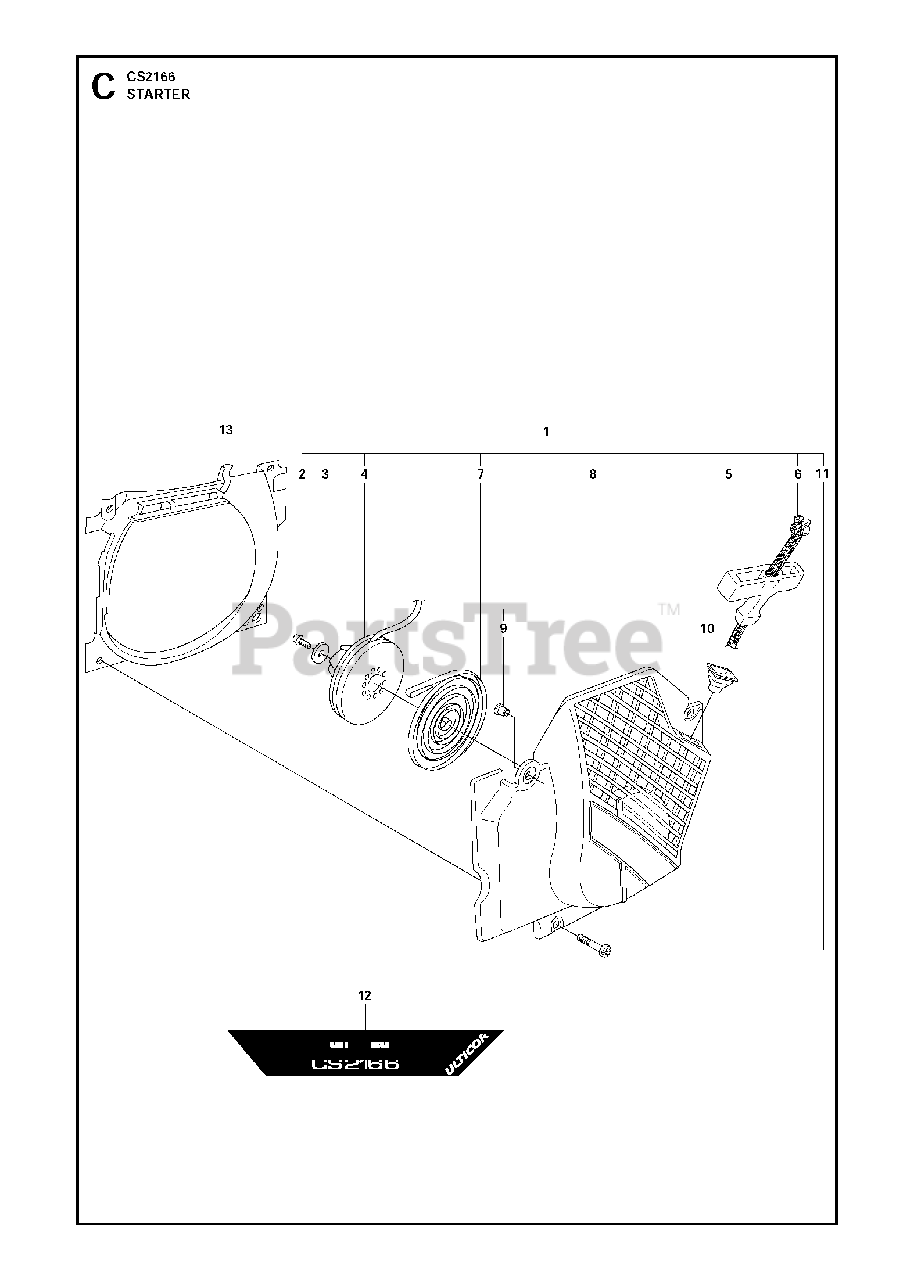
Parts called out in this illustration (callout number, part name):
1	STARTER ASSY
2	SCREW
3	WASHER
4	STARTER PULLEY
5	STARTER HANDLE
6	STARTER ROPE
7	SPRING
8	STARTER HOUSING
10	SLEEVE
11	SCREW
13	AIR CONDUCTOR
